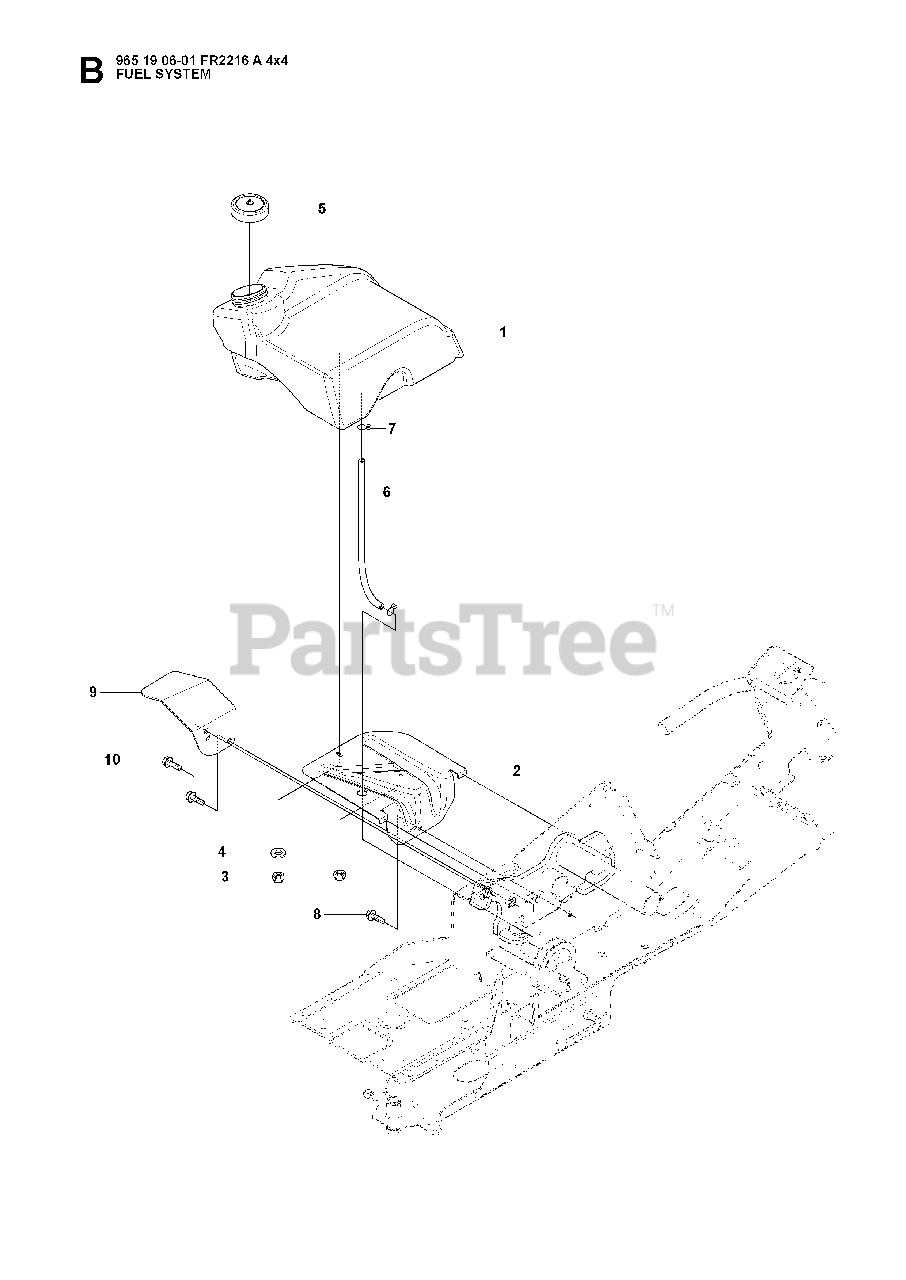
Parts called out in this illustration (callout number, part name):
3	LOCKNUT M6
4	WASHER
10	SCREW M10X25
